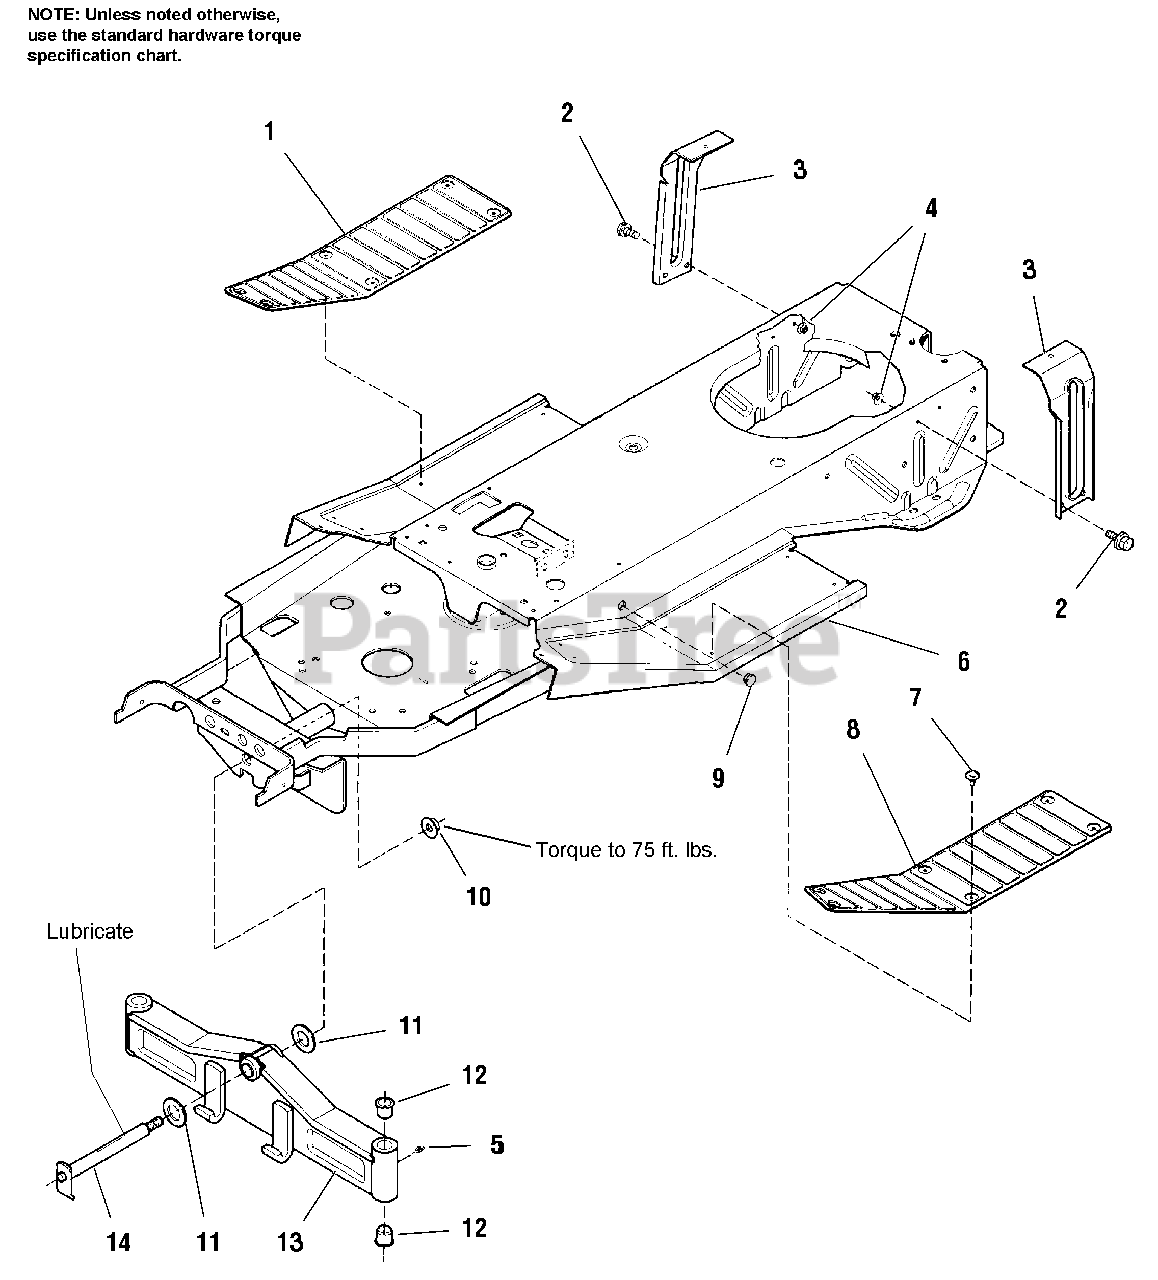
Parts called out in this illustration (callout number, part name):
1	PAD, Footrest, RH
2	CAPSCREW, Hex Flange Hd, Whizlock, 3/8-16 x 1
3	SUPPORT, Seat
4	NUT, Hex Nylon Lock, 3/8-16
5	GREASE FITTING
6	FRAME ASSY.
7	FASTENER, Panel
8	PAD, Footrest, LH
10	NUT, Hex Full, Lock, 3/4-16
11	WASHER, Special
13	AXLE ASSY., Front
14	AXLE PIVOT ASSY.
